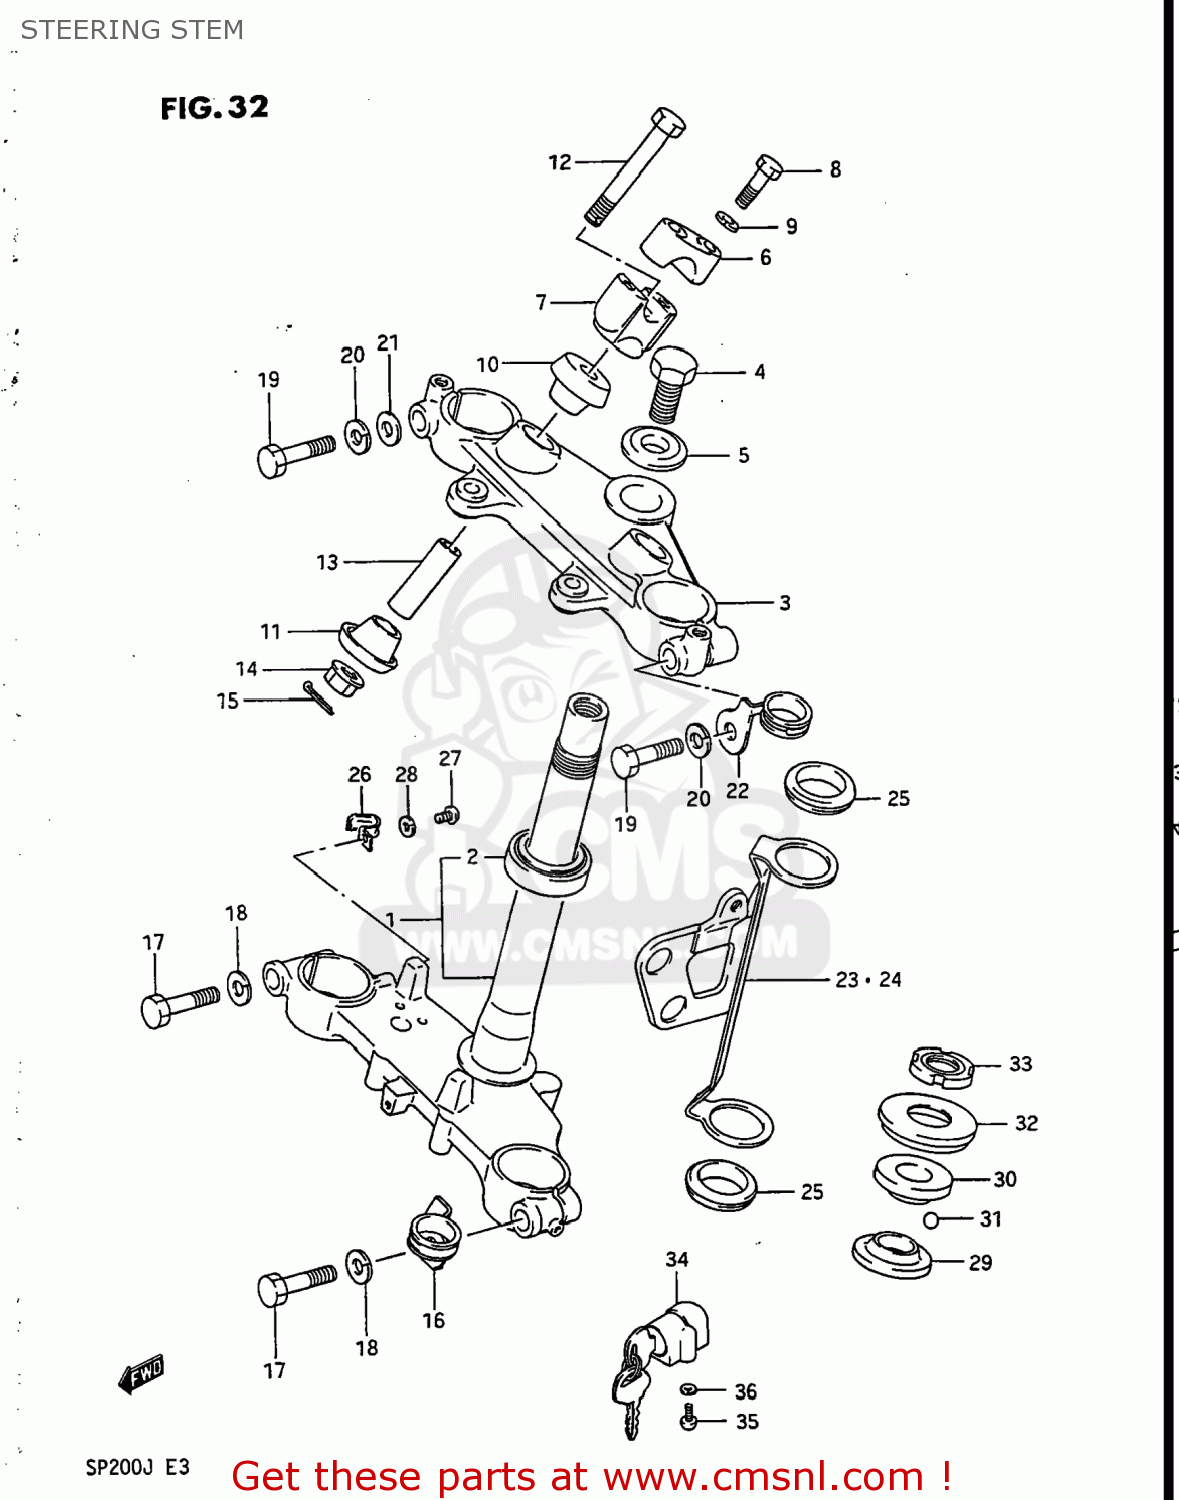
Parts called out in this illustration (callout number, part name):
1	STEM,STEERING
2	BEARING
3	HEAD,STEERING STEM
4	BOLT,STEERING STEM HEAD
5	WASHER
6	HOLDER,HANDLE UPR
7	HOLDER,HANDLEBAR LWR
8	BOLT
9	LOCK WASHER
10	RUBBER,HANDLE HOLDER
11	RUBBER,LWR
12	BOLT
13	SPACER
14	NUT
15	COTTER PIN
16	CLIP,LOWER
17	BOLT,INNER TUBE FITTING
18	WASHER,LOCK
19	BOLT,INNER TUBE FITTING
20	WASHER,LOCK
21	WASHER 10MM
22	CLIP,UPPER
23	BRACKET,HEADLAMP,R
24	BRACKET,HEADLAMP,L
25	CUSHION,HEADLAMP HSG BRACKET
26	CLIP
27	SCREW
28	WASHER,LOCK
29	RACE,STEERING INNER (SUJ)
30	RACE,STEERING,OUTER,UPPER
31	BALL
32	SEAL,STEERING UPR DUST
33	NUT,STEERING STEM
34	LOCK ASSY,STEERING
35	SCREW
36	LOCK WASHER
